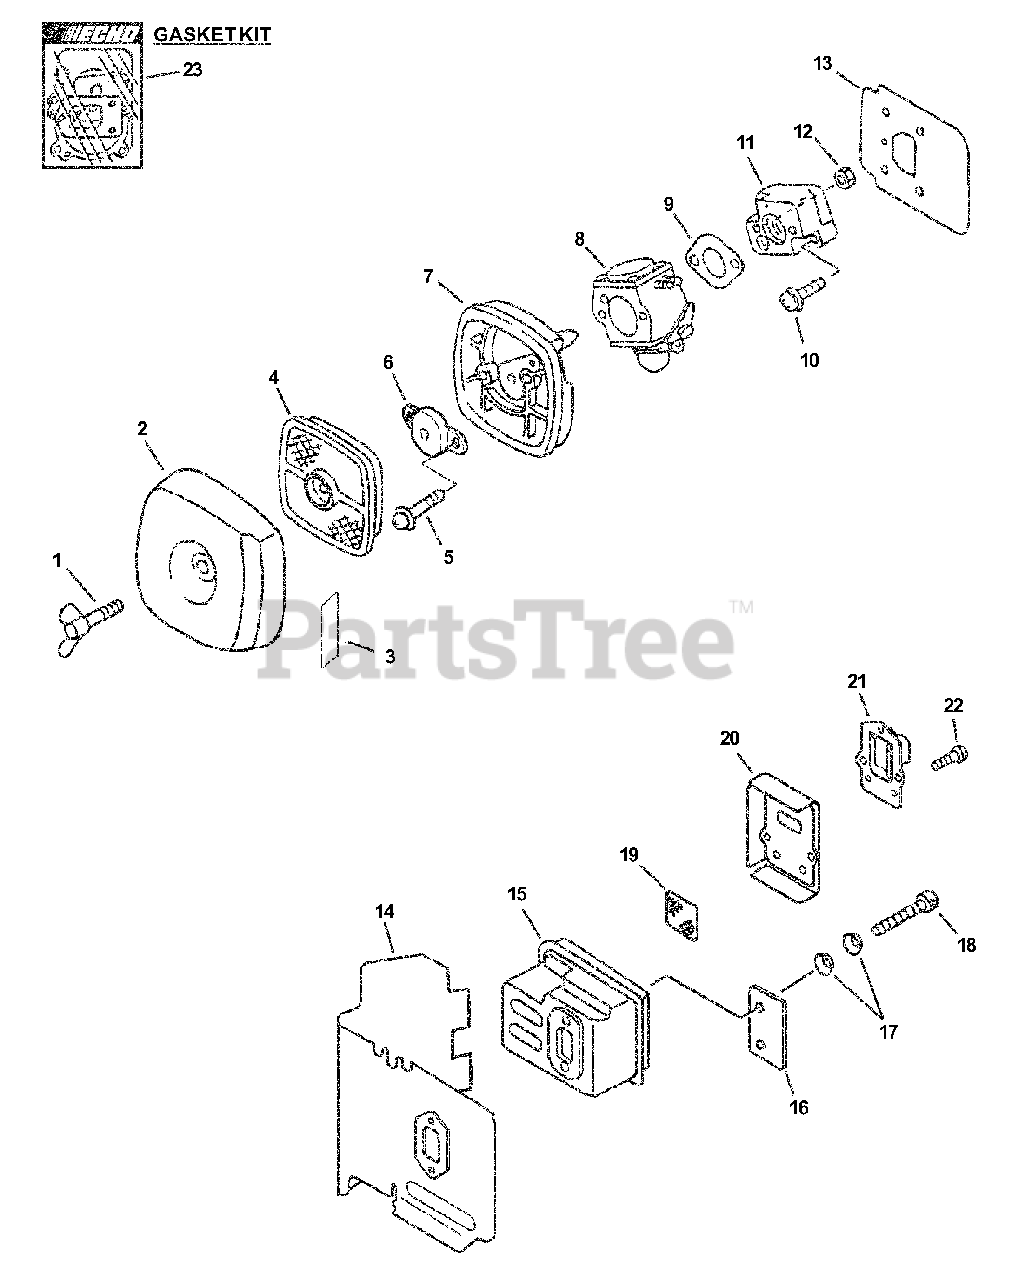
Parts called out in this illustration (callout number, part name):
1	THUMBSCREW
2	COVER, AIR FILTER - GRAY
3	LABEL - CHOKE
4	FILTER, AIR - SINGLE LAYER
5	SCREW - 5X65
6	PLATE, PREVENT
7	CASE, AIR FILTER - GRAY
8	CARBURETOR C1U-K58
9	GASKET, INTAKE
10	SCREW - 5X20
11	INSULATOR, INTAKE
13	SHIELD, INTAKE
14	SHIELD, EXHAUST
15	MUFFLER
17	WASHER - CONICAL
18	SCREW - 5X55
19	SCREEN, SPARK ARRESTOR
20	GASKET, EXHAUST
21	GUIDE, EXHAUST
22	SCREW - 4X10
23	GASKET KIT
